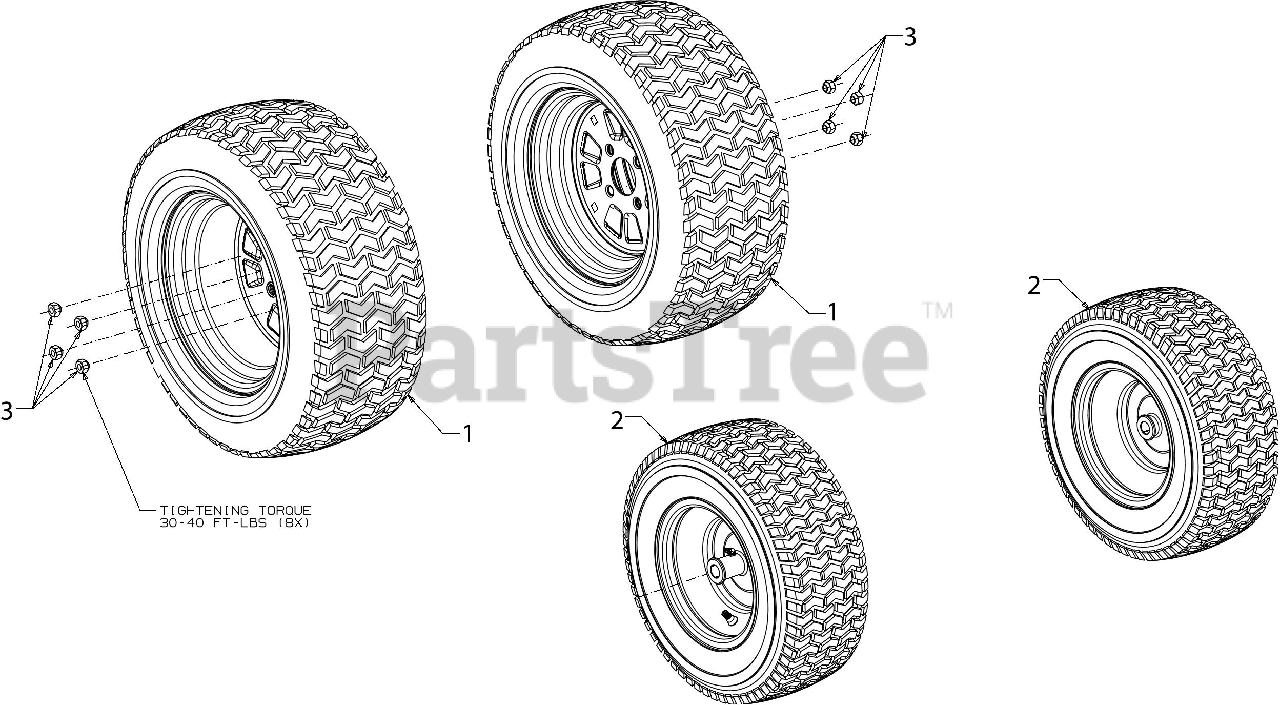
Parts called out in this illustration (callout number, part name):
1	WHEEL ASSEMBLY (22 x 9.5 x 12)
2	WHEEL ASSEMBLY (16X6.5X8)
3	LUG NUT 7/16-14
